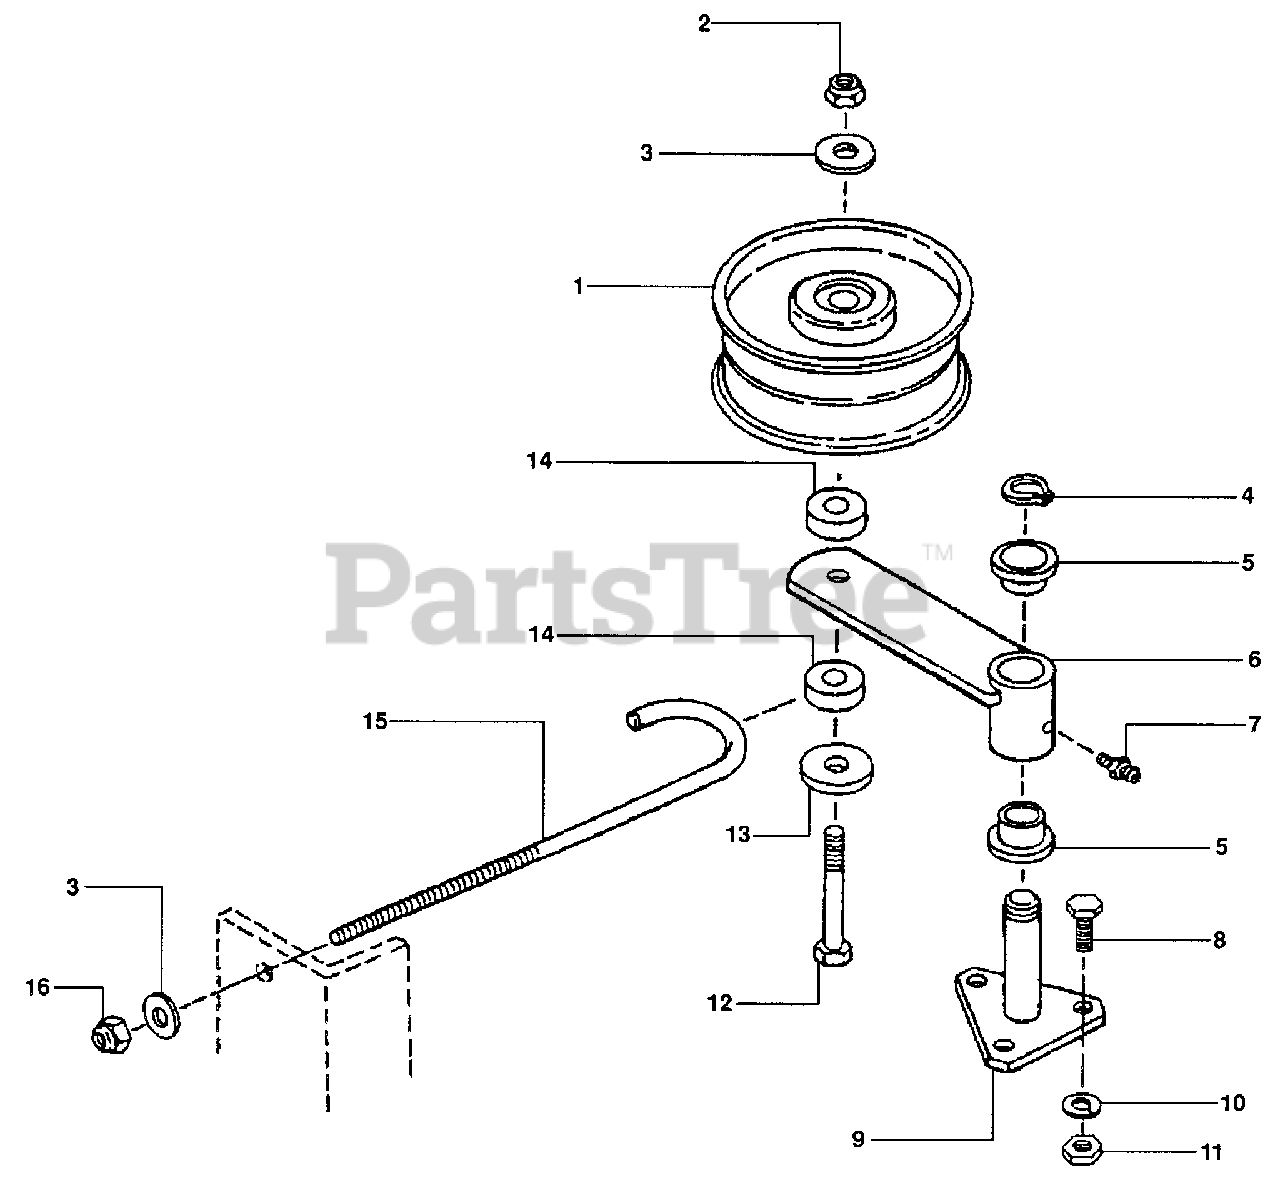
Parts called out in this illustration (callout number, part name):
1	PULLEY, Idler (5.00 O.D.)
2	NUT, 3/8-16 Hex Nyloc
3	WASHER,.44" I.D. X 1" O.D.
4	RING, 1" Retaining
5	BUSHING
6	IDLER ARM (Weldment)
7	FITTING, Lube
8	BOLT, 3/8-16 X 1" Hex Head Cap
9	PIVOT, Idler Arm
10	WASHER, 3/8" Split Lock
11	NUT, 3/8-16 Hex, Grade 5
12	BOLT, 3/8-16 X 2 3/4" Hex Head Cap, Grade 5
13	WASHER, 13/32" Flat
14	BUSHING, .38" I.D. X 1" O.D. X .410"
15	HOOK, "J"
